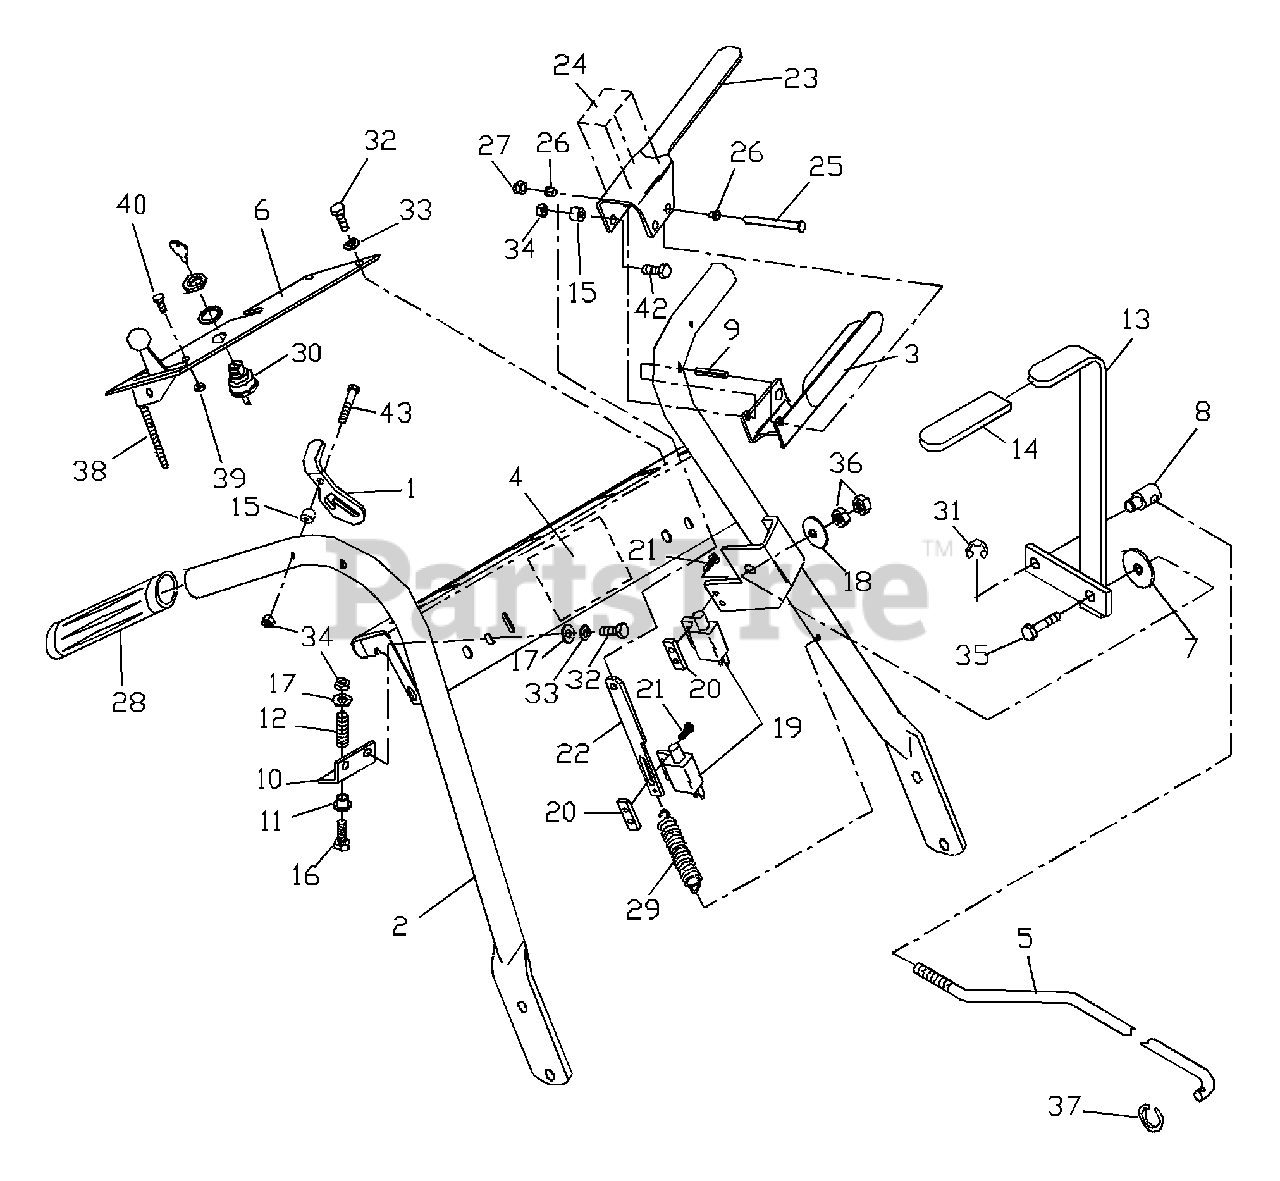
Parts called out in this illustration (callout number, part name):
1	THUMB LATCH RT.
2	HANDLE W/DECAL
3	CONTROL LEVER LT.
3	CONTROL LEVER RT.
4	DECAL, WARNING
5	BLADE LINK
6	ACCESS PLATE
7	FRICTION WASHER
10	DETENT WLDMT.
11	FLANGE BUSHING
13	BLADE LEVER WLDMT.
16	HCS 1/4C X 1.75
17	1/4 SAE WASHER
18	CONE WASHER
20	TAPPED PLATE
21	SCREW #10-24 X 5/8
22	O.P. LINKAGE
23	LEVER O.P. W/GRIP
24	DECAL, THUMB LATCH
25	PIN, CLEVIS
28	GRIP HANDLE
30	KEY SWITCH, COMPLETE
31	3/8 E-RING
32	HCS 1/4C X 3/4
33	1/4 SLOTTED LOCK WASHER
34	NUT 1/4C CENTERLOCK
35	HCS 3/8C X 1.5
36	NUT 3/8C CENTERLOCK
37	RING, RETAINER
38	THROTTLE CABLE (14 KAW.)
38	THROTTLE CABLE (17 KAW.)
39	#10-24 NYLOC NUT
40	HCS #10-24 X 1/2
42	HCS 1/4C X 1
43	HCS 1/4C X 2
